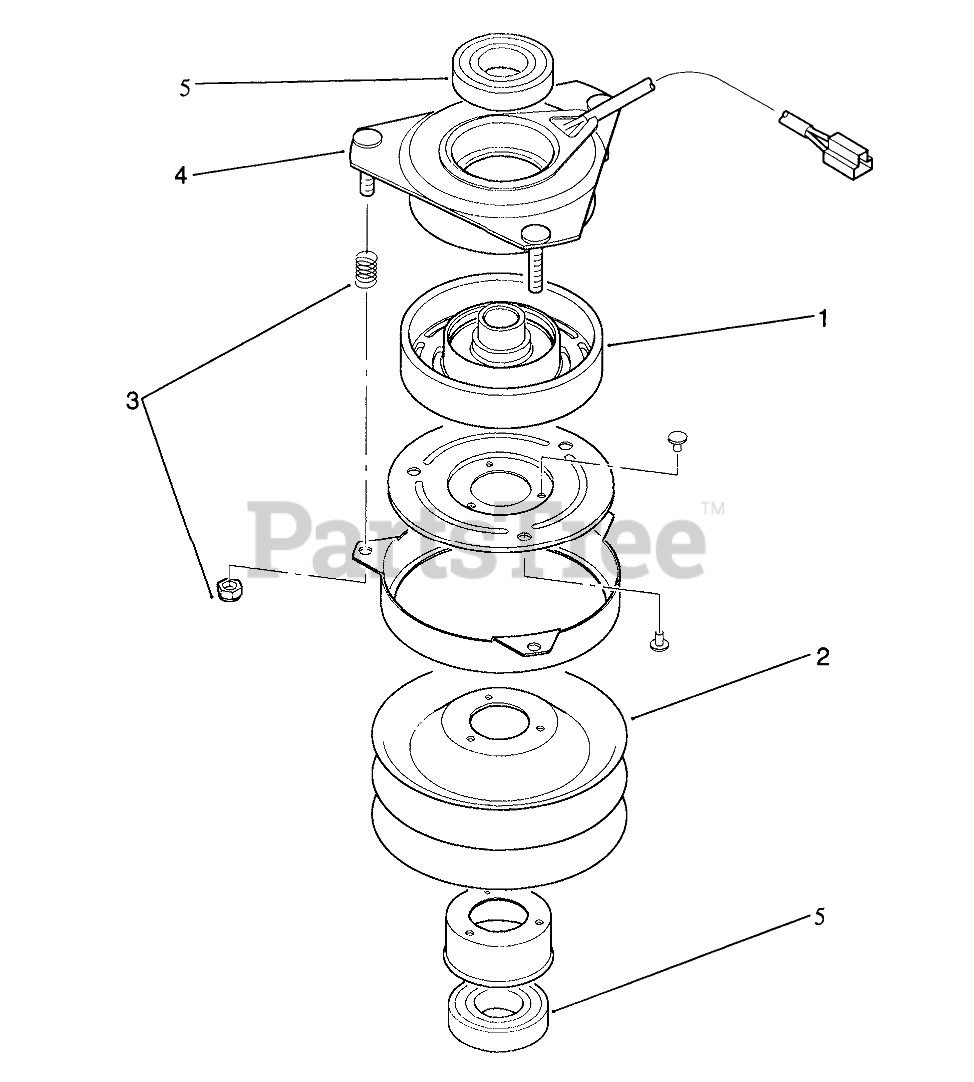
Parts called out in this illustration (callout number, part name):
1	ASS'Y-ROTOR
2	ASS'Y-ARMATURE
3	ACC-NUTS & SPRINGS
4	ASS'Y-FIELD
5	BEARING-ELEC CLUTCH
